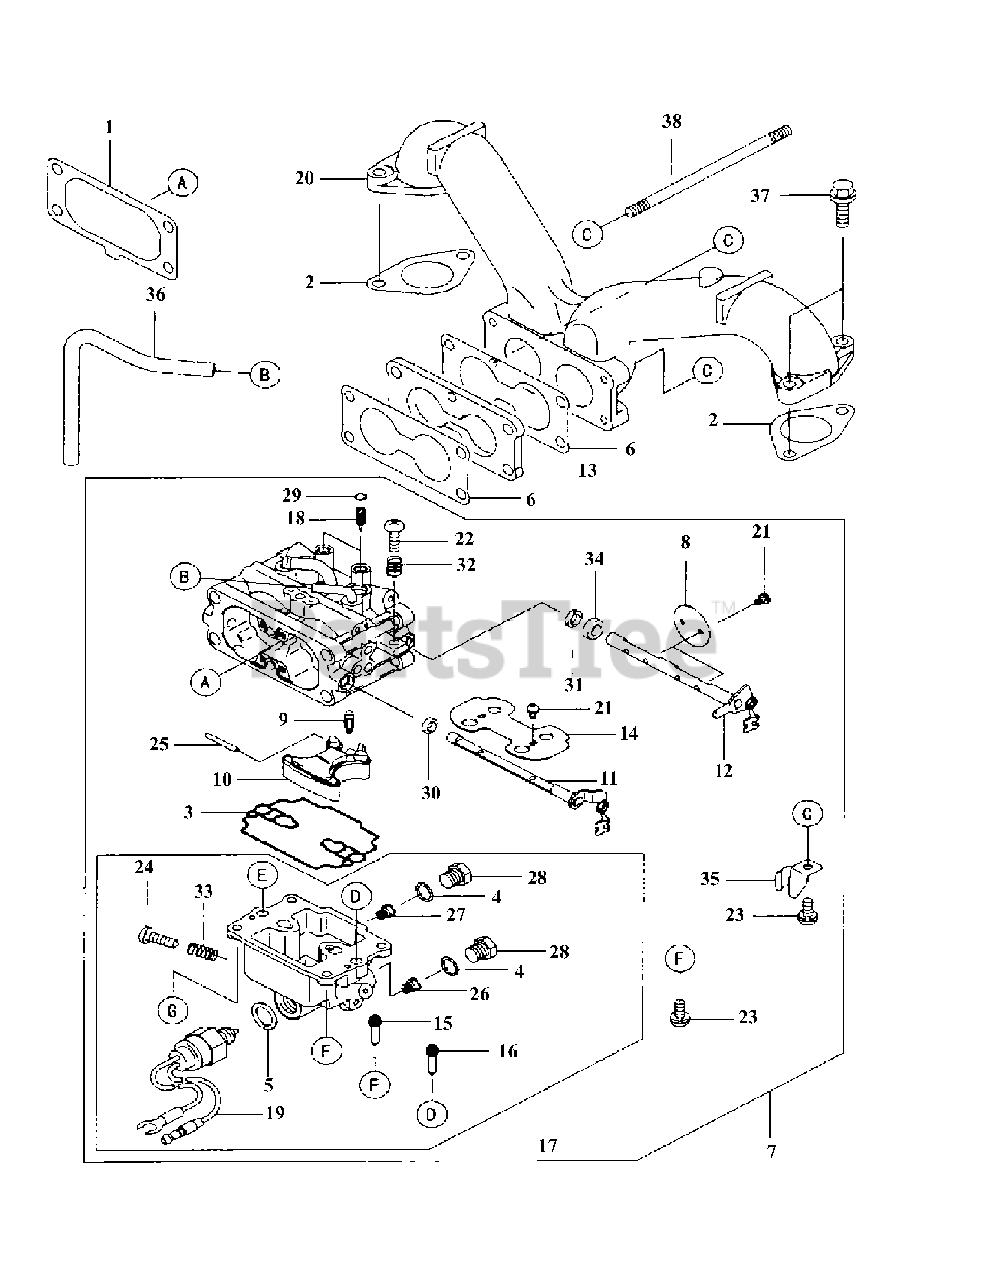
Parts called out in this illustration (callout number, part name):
1	Gasket, Air Filter
3	Gasket, Float Chamber
4	Gasket, Main Plug
5	Gasket,Solenoid
6	Gasket, Carburetor-Assy
7	Carburetor-Assy
8	Valve-Throttle
11	Shaft-Carburetor, Choke
12	Shaft-Carburetor
17	Chamber-Assy-Float
20	Manifold-Intake
28	Plug, Main, Jet
29	Plug, Expansion
